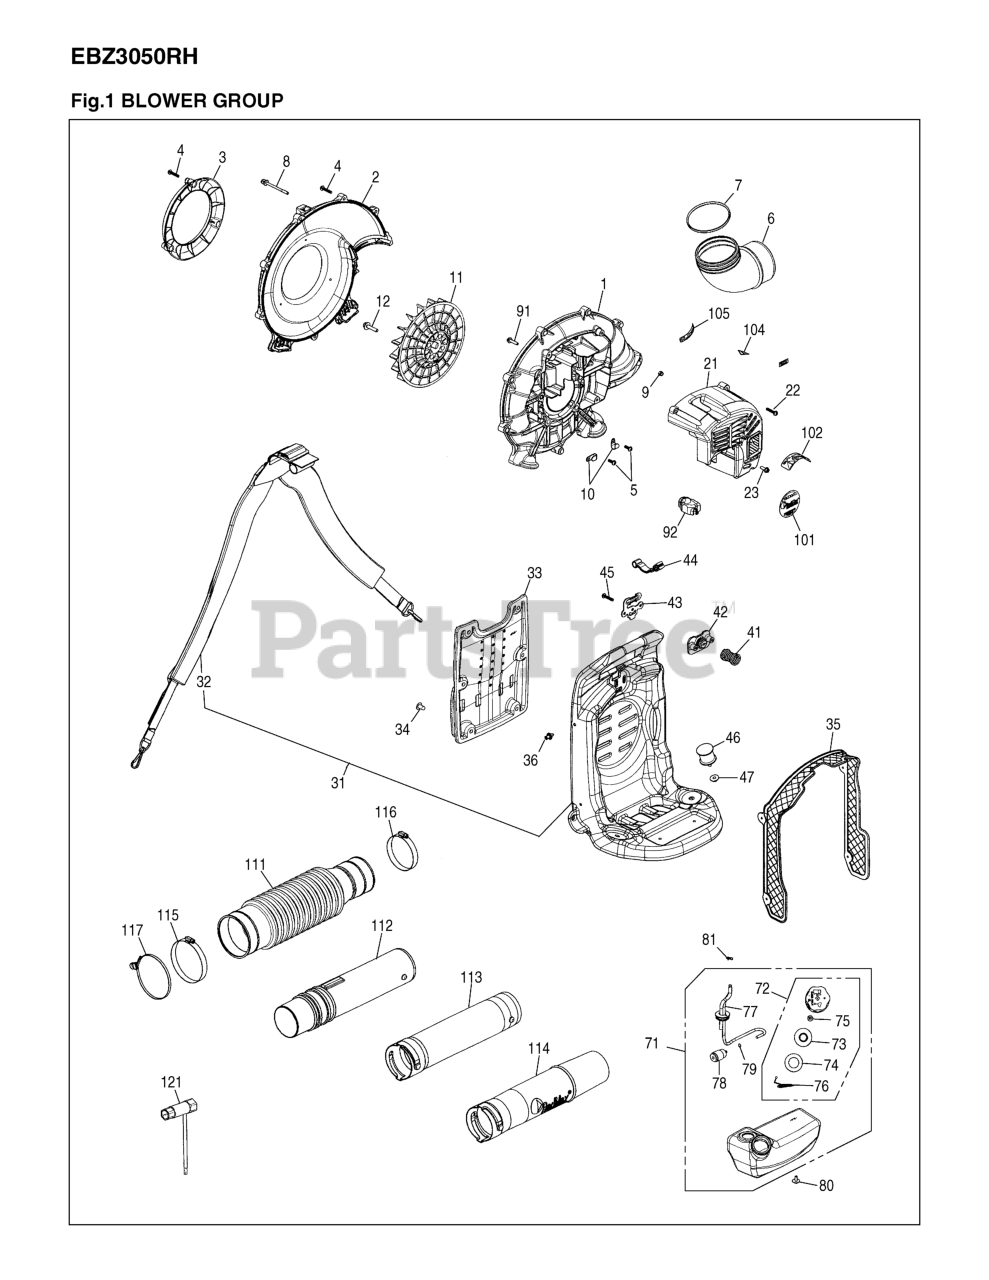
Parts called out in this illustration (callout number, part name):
1	VOLUTE CASE
2	VOLUTE COVER
3	FUNNEL
4	SCREW
6	ELBOW
8	SCREW TORX
9	NUT (B)
10	CLAMP (RPLS 1140-72231)
12	BOLT
21	COVER, ENGINE
22	SCREW
23	BOLT, TORX
31	FRAME ASSY
32	BAND ASSY (RPLS 848L213610)
33	PAD
34	CLIP (RPLS 3490-21320)
35	NET
36	CLIP (RPLS 3490-21320)
42	HOLDER, SPRING
45	SCREW
46	DAMPER, LOWER
47	NUT, M6
71	TANK ASSY
72	CAP ASSY
73	HOLDER (REPLACES -85230)
74	PACKING
75	FILTER
77	PIPE COMP
78	FUEL FILTER (BLK SLEEVE)
79	CLIP (REPLACES 2841-31280)
80	SCREW TORX
81	CLIP
91	BOLT
92	COVER
101	LABEL, RECOIL
102	LABEL CE CAUTION
104	LABEL, HOTMARK
105	LABEL, SOUND
111	HOSE (RPLS 2750-51110)
112	SWIVEL-JOINT (REPLACES -51200)
113	PIPE, STRAIGHT
114	PIPE, END
117	BAND
